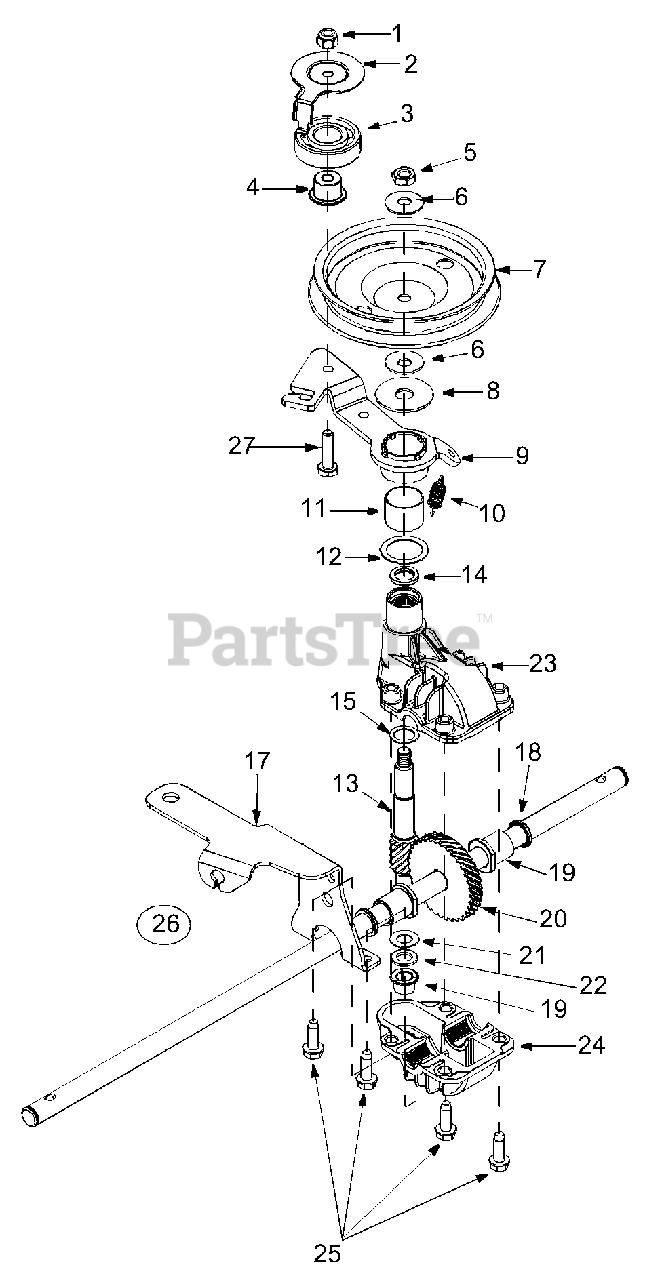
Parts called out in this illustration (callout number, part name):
2	Belt Keeper
3	Ball Bearing
4	Flange Bearing
5	Hex Jam Nut 5/16-24
6	Bell Washer .325 x .930 x .45
7	Pulley, 3.82 x .313 x .68
8	Flat Washer .422 x 1.38 x .060
9	Front Idler Assembly
10	Extension Spring
11	Bearing Sleeve
12	Fl-Wash. .865 x 1.145 x .030
13	Pinion Shaft
14	Needle Bearing .438 x .625 x .500
15	Flat Washer .504 x .700 x .030
17	Cable Idler Brkt.
18	Oil Seal
19	Flange Bearing
20	Output Shaft
21	Thrust Washer .375 x .070 x .030
22	Thrust Washer .388 x .625 x .062
23	Upper Housing
24	Lower Housing
25	Hex Screw w/Washer 1/4-20 x .750
26	Transmission Assembly Comp.
27	Hex Screw 1/4-28 x 1.0
